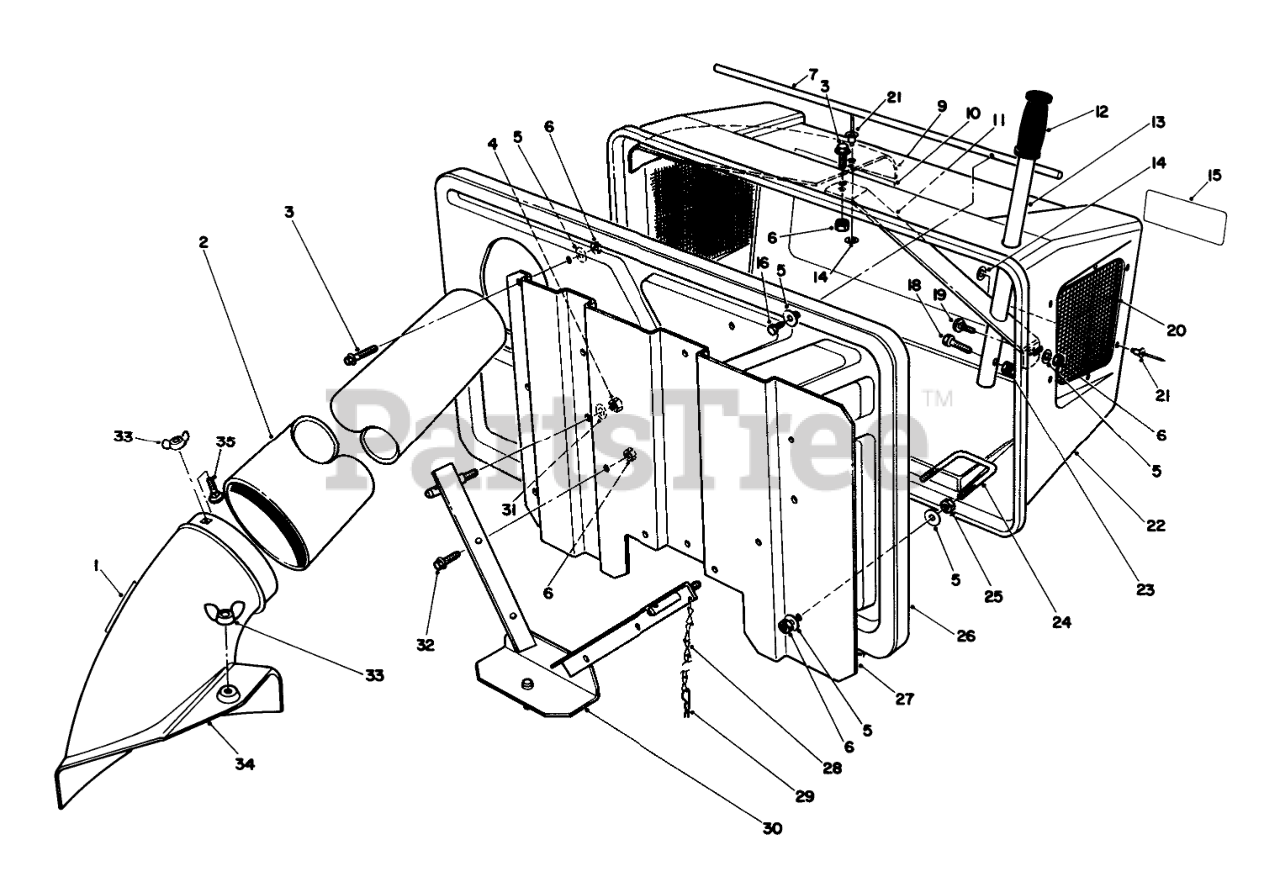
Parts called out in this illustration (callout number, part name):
1	DECAL-DANGER
3	SCREW-HHF
4	NUT-LOCK, NI
5	WASHER-FLAT
6	NUT-LOCK, NI
7	PIVOT ROD
9	DEFLECTOR
10	DECAL
11	HANDLE GUIDE
13	HANDLE TUBE
14	WASHER-FLAT
15	EASY EMPTY BAG DECAL
16	SCREW-HH
18	SCREW-HH
19	BOLT-CARR
20	SCREEN
21	RIVET-POP
22	HOPPER
23	NUT-HEX, SIDE DEFORM
24	LATCH
25	NUT-HEX
27	Plate-Mounting
28	6-LINK CHAIN W/HOOK
29	PIN-HAIR
30	V-Bracket
31	WASHER-FLAT
32	SCREW-HH
33	NUT-WING SPECL
34	Chute
35	BOLT-CARR
